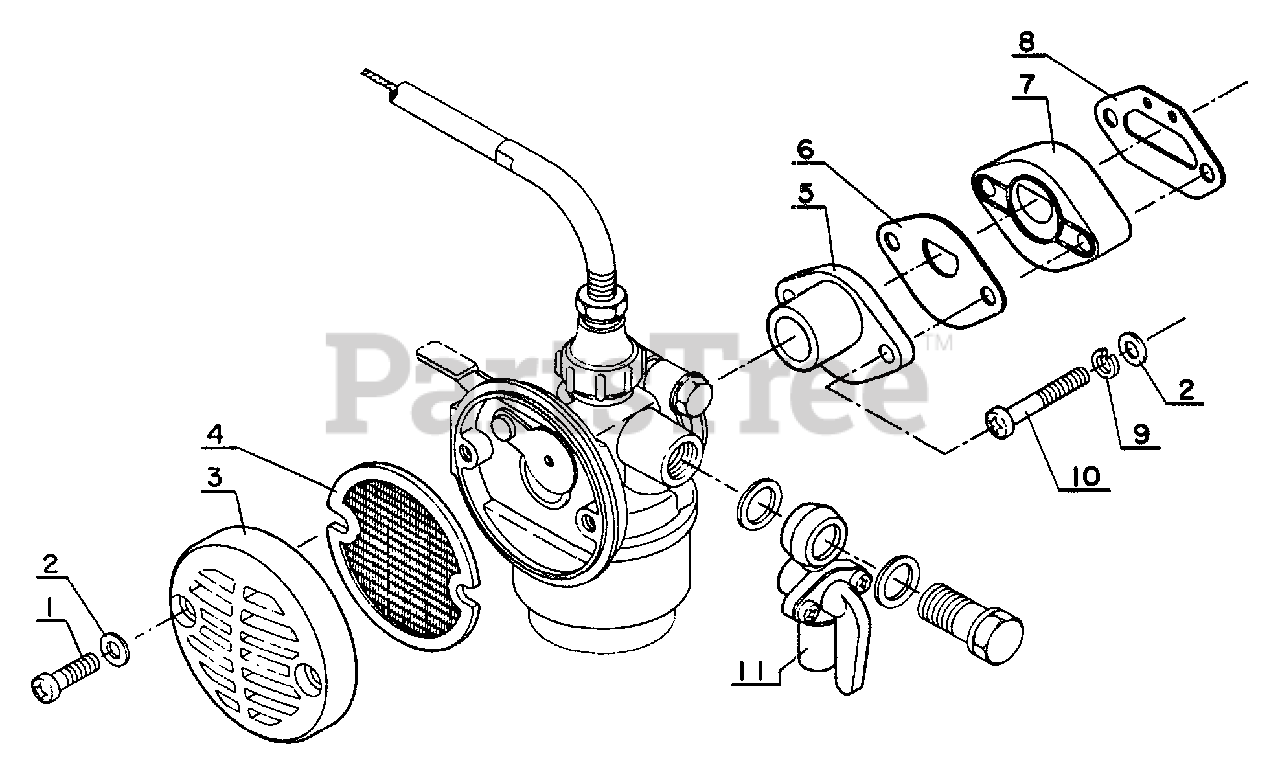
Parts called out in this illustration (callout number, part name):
1	SCREW 4×12
2	WASHER 4 MM
3	COVER, AIR FILTER
4	FILTER, AIR
5	ADAPTER, INTAKE
6	PACKING
7	INSULATOR, INTAKE
8	GASKET, INTAKE
9	WASHER, SPRING 4 MM
10	SCREW 4×25
11	FUEL VALVE ASSY
